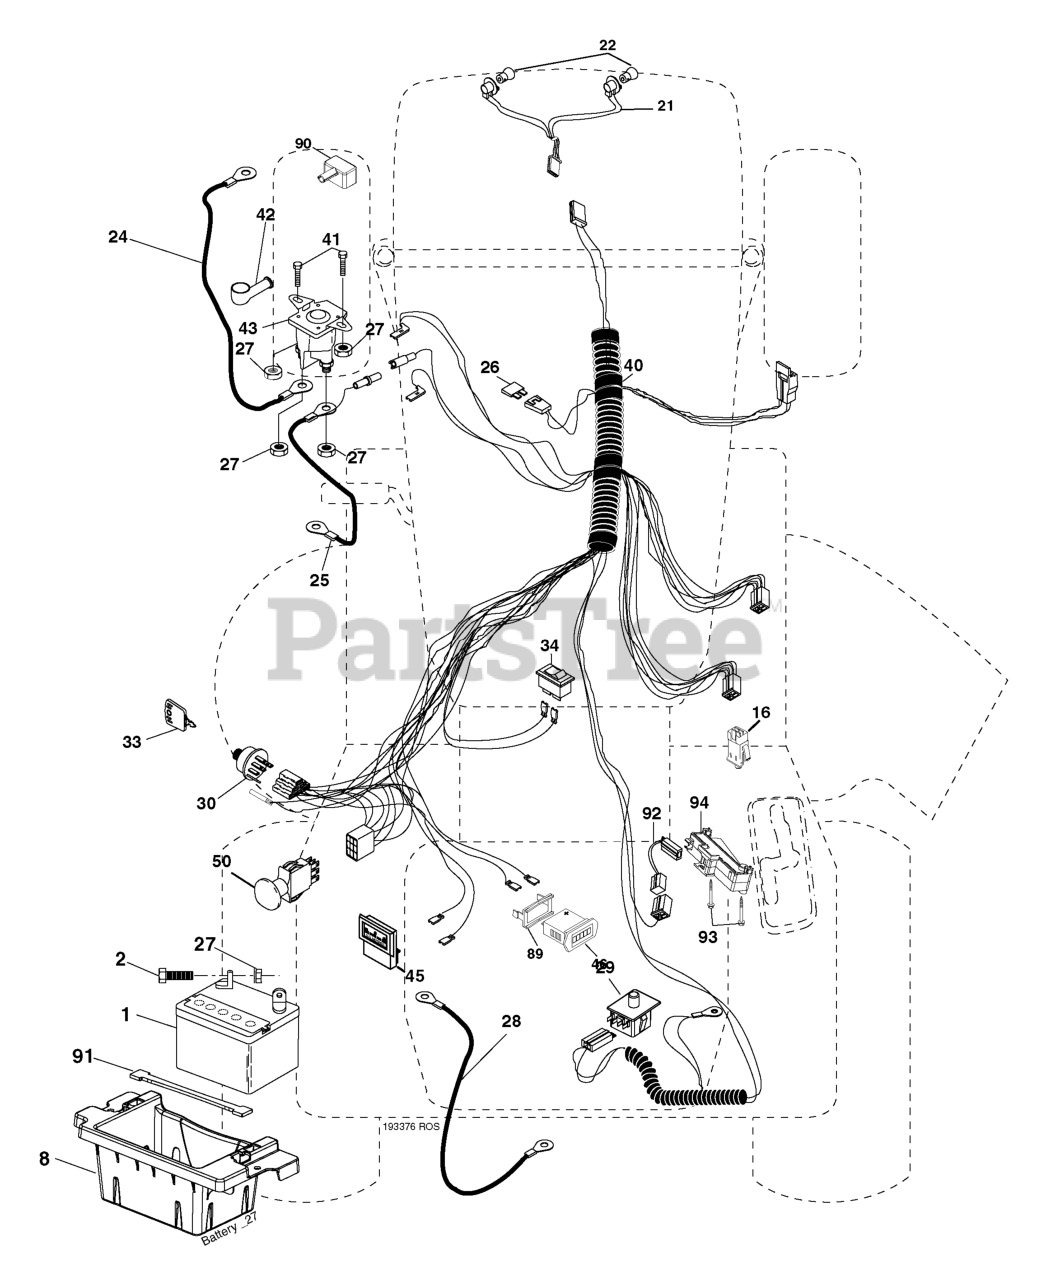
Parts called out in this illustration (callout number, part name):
1	BATTERY 12V .35 AMP
2	BOLT.HEX.1/4.X.3/4.DICHROMATE
8	BOX.BATTERY.MOUNT.FRONT.LT
16	SWITCH INTERLOOK PUSH-IN
21	HARNESS ASSY LIGHT
24	BATTERY CABLE GT
25	CABLE BATTERY 6 GA 22" W/16W
26	FUSE 20AMP
27	NUT
28	CABLE GROUND 6 GA 21" 90T BLK
29	SWITCH.SEAT.DP W/RAMPS
30	SWITCH.IGN.DELTA.W.LGH.ROS
33	KEY MLD GEN DELTA
40	HARNESS.IGN.ELECT.STL
41	BOLT
42	TERMINAL COVER
43	SOLENOID
46	HOUR METER
50	RP.PTO.SWITCH.8 TERMINAL.BLACK
55	Screw Thdrol 5/16-18 x 1/2
89	BRACKET SNAP-IN HOURMETER
90	COVER TERMINAL
91	STRAP.BATTERY.MOUNT.FRONT(2 2)
92	HARNESS.PIGTAIL.REVERSE.SWITCH
93	SCREW.PLASTITE
94	MODULE.REVERSE.ROS
